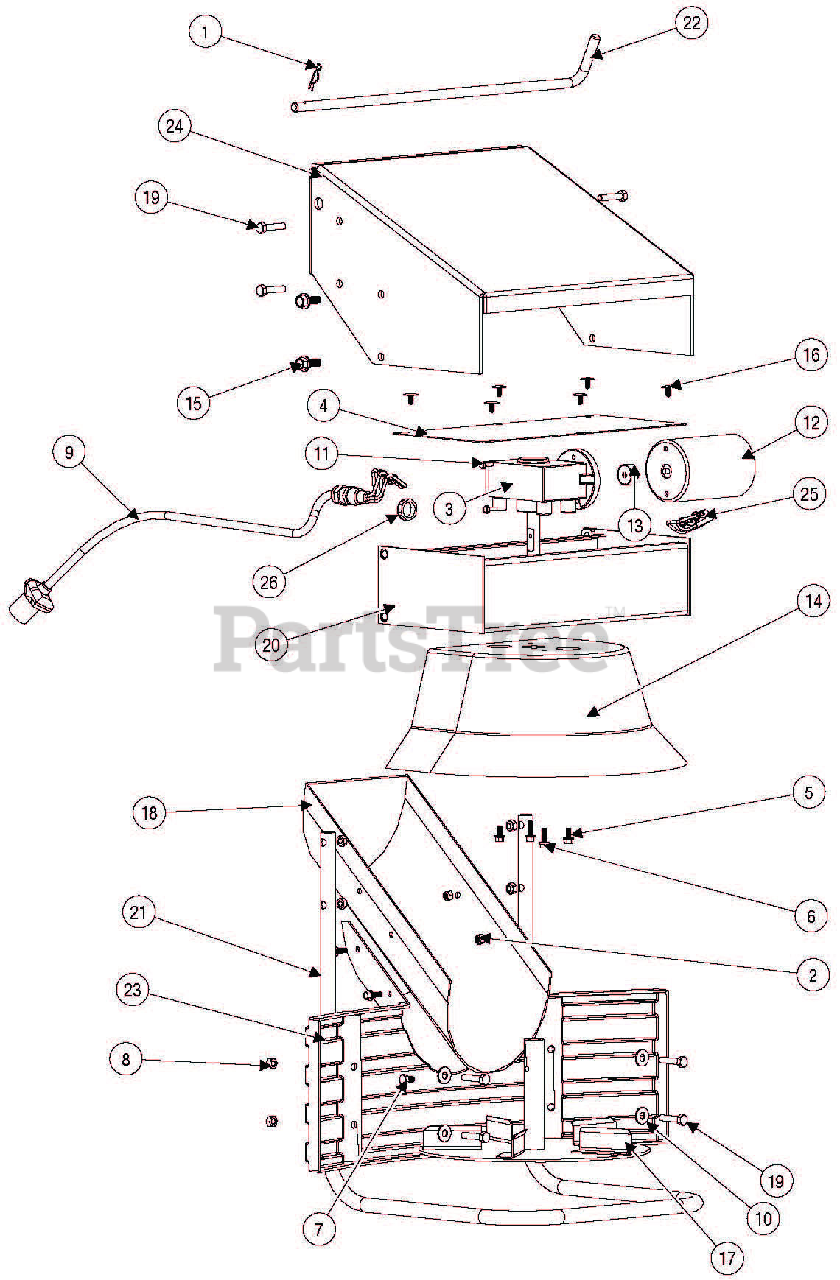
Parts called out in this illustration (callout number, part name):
1	HAIR PIN COTTER .093 X 2-3/8, ZINC
3	TRANSMISSION8:1, WORM GEAR
4	COVERSPINNER DRIVE ENCLOSURE
5	BOLT, 1/4-20 X 1/2 SERR FLANGE, STAINLESS (5PK)
9	POWER CABLE 26-1/2
11	BOLT, #10-32 X 5/8 SERRATEDFLANGE, ZINC, W/PATCH (5PK)
12	MOTOR 3.0 X 3.8 12 VOLT DC
13	MOTOR DRIVE COUPLER
14	CE SHROUD
16	RETAINER, 1/4 X 3/4 X 1/2 6 PK
17	SPINNER W/ EXTENDED SHAFT, 12
18	MATERIAL CHUTE PRO TRUCK
20	SPINNER DRIVE ENCLOSURE
21	TUBULAR SPINNER GUARD PRO TRUCK
22	BENT PIN 1/2 X 20
23	SPINNER DEFLECTOR PRO TRUCK
24	DRIVE ENCLOSURE SHROUD
26	NUT, 5/16-18 BLACK NYLON2PK
